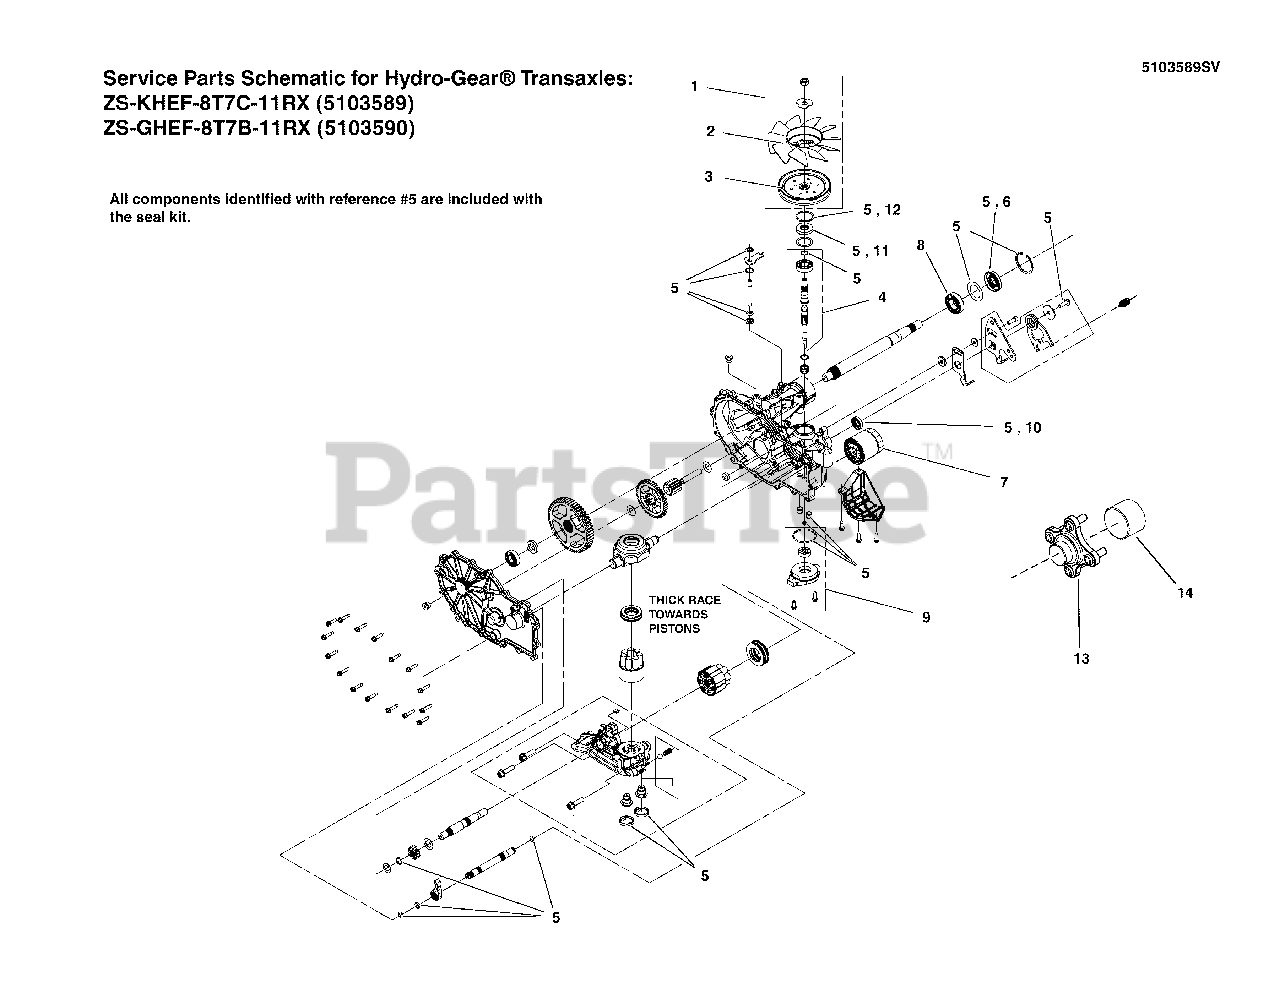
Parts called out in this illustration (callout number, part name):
1	KIT, FAN & PULLEY -
2	FAN, 7.0 -
3	KIT, PULLEY 5.0 -
4	KIT, INPUT SHAFT (BEARING AND SHAFT ONLY)
5	KIT, SEAL - HG# 73239
6	KIT, SEAL, AXLE - HG# 53699
7	FILTER, OIL, ZT2800
8	BEARING BALL, 1.0 X 52 X 15 OPEN 6205M
9	KIT, CHARGE PUMP, ZT2800, ZT3100
10	SEAL, CONTROL ARM, 18X32X7, #51140
11	OUTPUT SHAFT SEAL, 17X40X7, HR #51161
12	RING, RET 2.06 INT,
13	ASSM, HUB
14	AXLE CAP,
15	SEAL, .375 X .750 X .25 LIP, H/G 51626
1000	KIT, PLUG, BRAKE BORE, OUTBOARD
